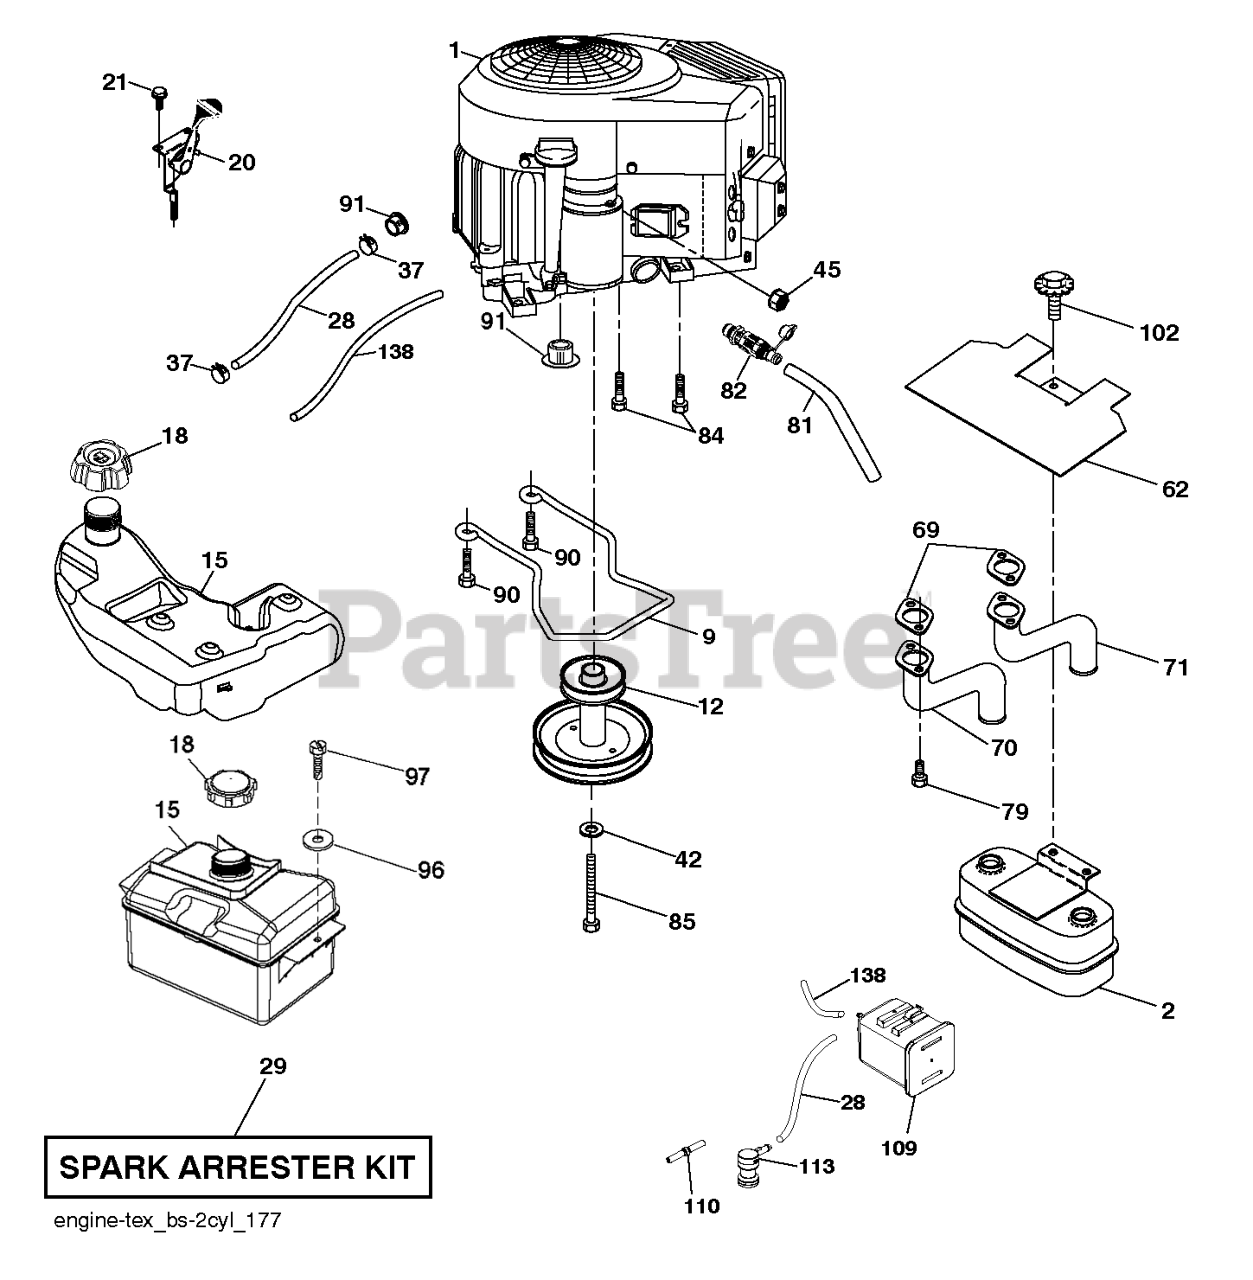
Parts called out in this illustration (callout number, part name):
2	MUFFLER.TWIN.CYL.LOW.TONE
2	MUFFLER.ASM.TWIN.MNTG.BRACKET
9	KEEPER.BELT.ENG.4.25"2.BLT.431
12	PULLEY.ENGINE
12	RP_PULLEY ENGINE
15	FUEL TANK
15	Tanks
15	FUEL TANKS
15	TANK.ASSEMBL.2.5GAL.NON-EPA
18	Fuel Caps
18	FUEL CAP
18	FUEL.CAP.ASM.2.25TETHRED.RATCH
18	CAP.ASM.FL.RITCH.3"E10.SYM.498
18	CAP.FUEL.2 WAY VENT
18	CAP.2.25'.VENTED.RATCHET.EPA
20	THROTTLE.COBRA.38"READSTART.BK
20	CONTROL.TH/CK.COBRA.B&S.TWN.BK
21	SCREW.#10 X 0.750.BOS
28	HOSE.1/4".LOW.PERM.FUEL.LN.22"
28	LINE.FUEL.20"FRONT.EMI
28	HOSE 1/4" LOW PERMEATION FUEL
29	KIT.SPARK ARRESTOR 794945 B&S
37	HOSE CLAMP
42	LOCKWASHER
45	NUT
62	SHIELD.HEAT.MUFFLER
69	GASKET.MUFFLER
70	EXHAUST.TUBE.LH.BS/TWIN
71	EXHAUST.TUBE.RH.B&S.TWIN.INTEK
79	SCREW.SOCKET.HEAD.5/16-18
81	TUBE, DRAIN OIL ASM.
82	VALUE.OIL.DRAIN
84	SCREW.3/8-16
85	BOLT.HEX.7/16-20X4.GR5.1.5BLUE
90	SCREW 3/8-16X1
91	BUSHING.1.375OD
96	WASHER
96	Washers
97	SCREW HEXWSHR 1/4-20X3/4
102	SCREW
102	BOLT.5/16-18UNCX3/4 W/SEMS.BLK
102	BOLT 5/1618UNC X 3/4 W/ SEMS
109	CANNISTER, CARBON
110	VALVE.ASM.ANTI-SLOSH
113	VALVE.SLANT.CARTRDG.90 DEG.TEX
138	PURGE.LINE.36"REAR.CALIFORNIA
138	TUBE.PURGE.FUEL.1875
138	Hoses
